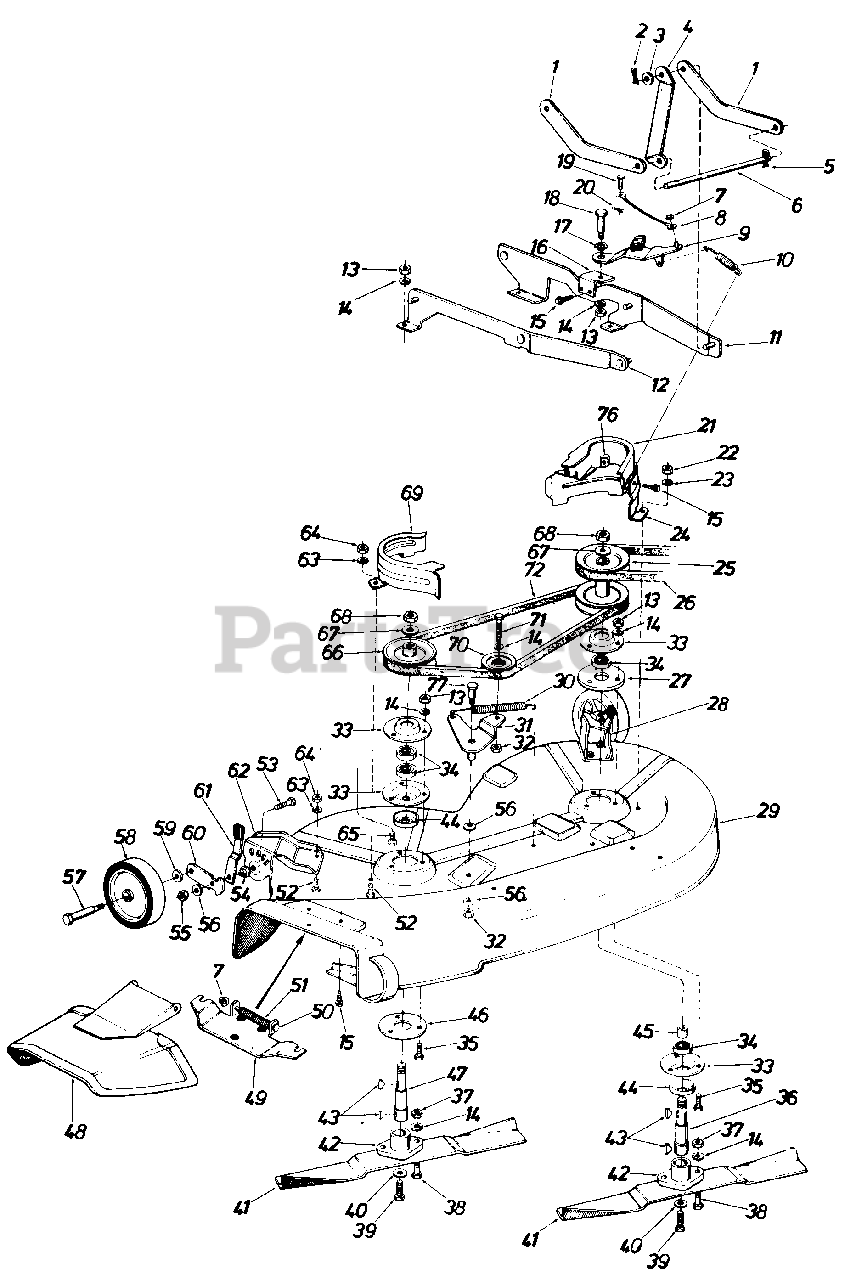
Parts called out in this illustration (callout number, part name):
3	Fl-Wash. 50" I.D. x 1.00" O.D. x .090 Thk.
6	Deck Connecting Rod
7	Push Cap 1/4" Rod
8	Brake Cable Ass'y.
9	Spindle Brake Arm Ass'y.
10	Extension Spring
11	Hanger Brkt. Ass'y. - L.H. Side
12	Hanger Brkt. Ass'y. - R.H. Side
13	Hex Nut 5/16-18 Thd.*
14	L-Wash. 5/16" I.D.*
15	Hex Wash. Hd. Self-Tap Scr. 1/4-20 x .50" Lg.
16	Spindle Brake Pivot Brkt.
17	Wave Wash. .438" I . D. x .750" O. D. x .15 Thk.
18	Shld. Bolt.437" Dia. x .162" Lg. 5/16-18 Thd.
19	Clevis Pin 1/4" Dia. x 1.00" Lg.
20	Hairpin Cotter 1/4" Dia.
21	Upper Belt Guard - L.H. Side
22	Hex Nut 1/4-20 Thd.*
23	L-Wash. 1/4" I.D.*
24	Lower Belt Guard-L.H. Side
25	Deck Drive Pulley
26	"V"-Belt 1/2" x 51.0" Lg. (Kevlar) "A" Sec.
27	Spindle Spacer Plate
28	Wheel Brkt.-L.H. Side
29	38" Deck Ass'y.
30	Extension Spring
31	Deck Idler Brkt. Ass'y.
32	Hex Cent. L-Nut 3/8-16 Thd.
33	Bearing Housing
34	Ball Brg. .787 I.D. x 1.85 O.D x .55
35	Hex Bolt 5/16-18 x 1.0" Lg.*
36	Blade Spindle
37	Hex Nut 5/16-24 Thd.*
38	Hex Bolt 5/16-24 x 1.00" Lg.*
39	Hex Bolt 3/8-24 x 1.50" Lg.*
40	L-Wash. 3/8" I.D. Heavy Duty
41	19" Blade
42	Blade Adpater Kit
43	#6 Hi-Pro Key 5/32 x 5/8" Dia.
44	Bearing Shield
45	Spacer.790" I.D. x 1.0" O.D x.315 Lg.
46	Deck Reinforcement Plate
47	Blade Spindle
48	Chute Cover Ass'y.
49	Adapter Plate
50	Hinge Pin
51	Torsion Spring
52	Hex Bolt1/4-20x.50" Lg.
53	Hex Bolt 3/8-16 x 1.25" Lg.*
54	Shoulder Spacer
55	Hex Jam L-Nut 3/8-16 Thd.
56	BellevilleWash..400" I.D. x 1.13" O.D. x .030
57	Shld. Bolt. 498 Dia. x 1.53" Lg.
58	Deck Wheel 5" Plastic-Comp.
59	Belleville Wash. .400" I.D. x .88" O.D. x .060
60	Wheel Pivot Bar-Deck
61	Spring Lever Ass'y. w/Knob
62	Wheel Brkt. - R.H.
63	L-Wash. 1/4" I.D.*
64	Hex Nut 1/4-2 Thd.*
64	Hex Nut 1/4-20 Thd.*
65	Sems Truss Hd. Scr. 5/16-18 x.50" Lg.
65	Sems Truss Hd. Scr. 5/16-18 x.50" Lg.*
66	Pulley 4.75" O.D.
67	L-Wash. 5/8" I.D.*
68	Hex Jam Nut 5/8-18 Thd.
69	Belt Guard
70	4" "V"-Idler Pulley
71	Hex Bolt 3/8-16x 1.25" Lg.*
72	"V"-Belt.50" x 53.0 Lg.(4L)
76	Speed Nut 1/4-20 Thd.
77	Shld. Bolt .50" Dia. x .71" Lg. 3/8-1 Thd.
